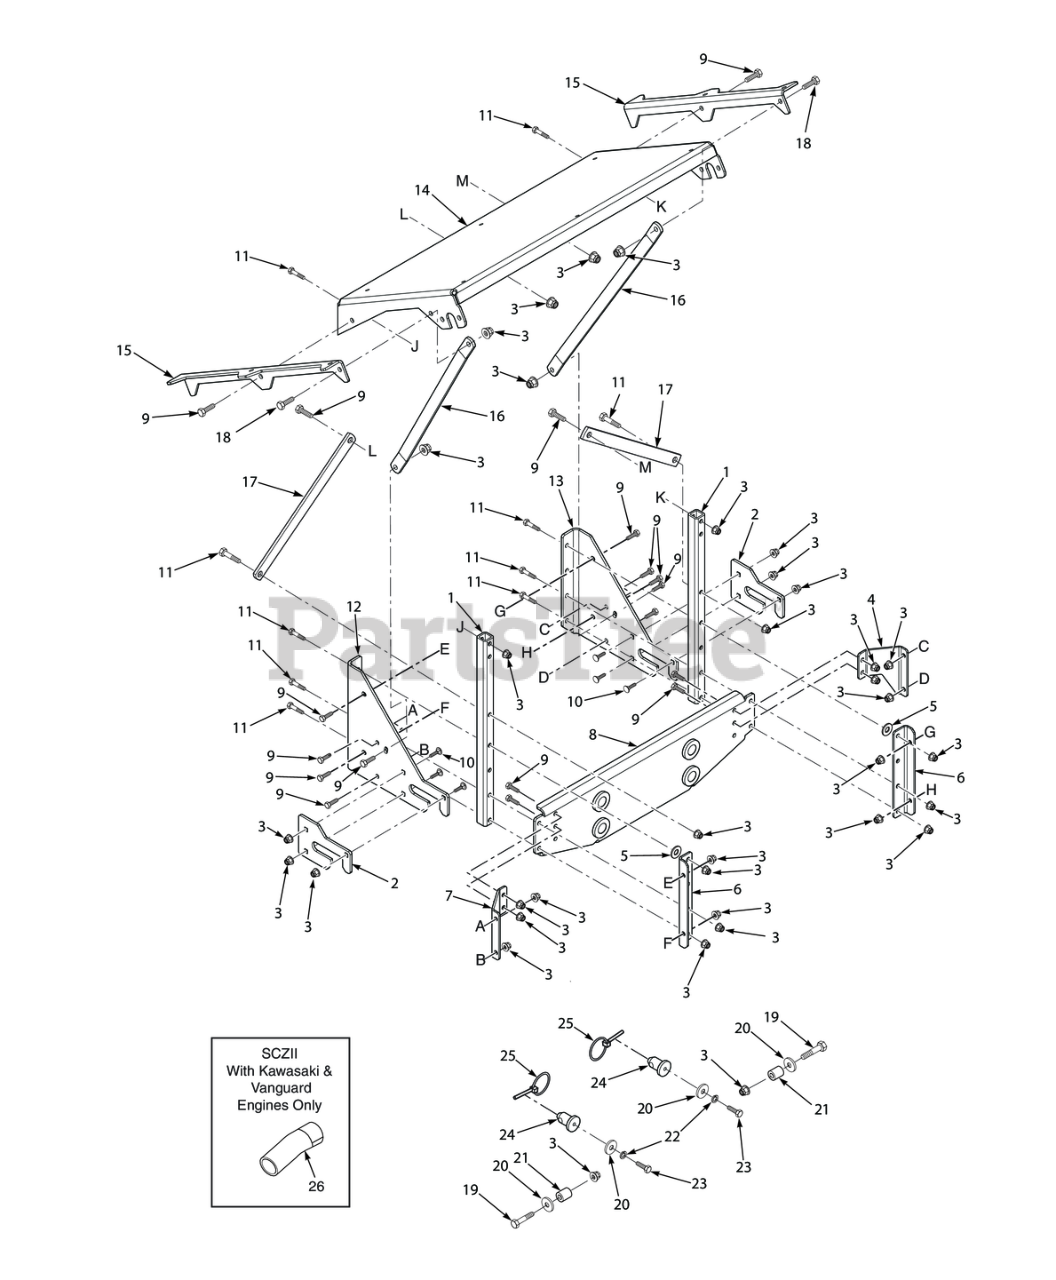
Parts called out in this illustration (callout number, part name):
1	Tube, Upright
2	Wear Plate, GC
3	Nut, Flange Elastic Stop Nut, 3/8-16
4	Angle Brace, LH GC
5	Flatwasher, 7/16-.469 x 1.75 x .25 (48, 52)
6	Mounting Bracket, GC Tube
7	Angle Brace, RH GC
8	Mounting Bracket Weldment
9	Bolt, Hex Head 3/8-16 x 1"
10	Carriage Bolt, 3/8-16 x 1.0"
11	Capscrew, Hex Head 3/8-16 x 2-1/2"
12	RH Mounting Bracket, GC
13	LH Mounting Bracket, GC
14	Support Frame, Hopper
15	Bracket, Hopper Support
16	Brace Stiffener, Short
17	Brace, Engine Mounting
18	Bolt, Hex Head, 3/8-16 x 1 Gr. 5
19	Bolt, Hex Head 3/8-16 x 2-1/4"
20	Flatwasher, 3/8-.406 x 1-1-1/2 x 7 Gauge
21	Spacer
22	Lockwasher, 3/8" Spring, Kawasaki FX / FS
23	Bolt, Hex Head 3/8-16 x 1-1/4" Grade 8
24	Pin, GC Locator
25	Quick Pin, 5/16" Dia.
26	Pipe, Muffler Extension - FX921
26	Pipe, Muffler Extension - 37 BV-EFI
